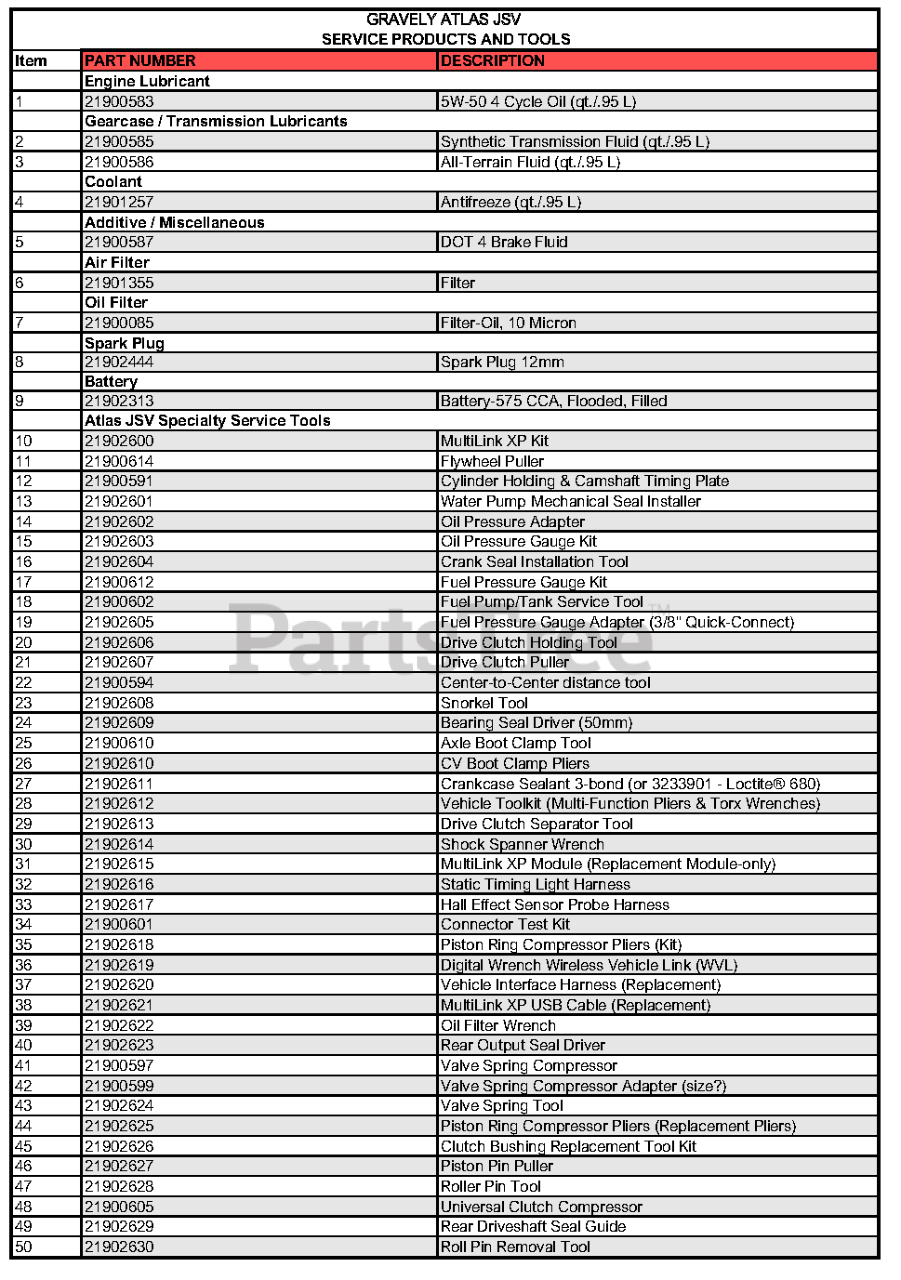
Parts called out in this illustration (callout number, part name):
1	5W-50 SYNTHETIC, 1 QT
2	TRANSMISSION FLUID-SYN, 1 QT
3	ALL TERRAIN FLUID, 1 QT
4	ANTI-FREEZE, ARIENS, 1QT
5	BRAKE FLUID-DOT 4, 12 OZ
7	FILTER-OIL,10 MICRON,(12)
8	SPARKPLUG-12MM
9	BATTERY-575 CCA,FLOODED,FILLED
10	MultiLink XP Kit
11	FLYWHEEL PULLER
12	Cylinder Holding & Camshaft Timing Plate
13	Water Pump Mechanical Seal Installer
14	Oil Pressure Adapter
15	Oil Pressure Gauge Kit
16	Crank Seal Installation Tool
17	Fuel Pressure Gauge Kit
18	Fuel Pump/Tank Service Tool
19	Fuel Pressure Gauge Adapter (3/8" Quick-Connect)
20	Drive Clutch Holding Tool
21	Drive Clutch Puller
22	Center-to-Center distance tool
23	Snorkel Tool
24	Bearing Seal Driver (50mm)
25	Axle Boot Clamp Tool
26	CV Boot Clamp Pliers
27	Crankcase Sealant 3-bond (or 3233901 - Loctite® 680)
28	Vehicle Toolkit (Multi-Function Pliers & Torx Wrenches)
29	Drive Clutch Separator Tool
30	Shock Spanner Wrench
31	MultiLink XP Module (Replacement Module-only)
32	Static Timing Light Harness
33	Hall Effect Sensor Probe Harness
34	Connector Test Kit
35	Piston Ring Compressor Pliers (Kit)
36	Digital Wrench Wireless Vehicle Link (WVL)
37	Vehicle Interface Harness (Replacement)
38	MultiLink XP USB Cable (Replacement)
39	Oil Filter Wrench
40	Rear Output Seal Driver
41	Valve Spring Compressor
42	Valve Spring Compressor Adapter (size?)
43	Valve Spring Tool
44	Piston Ring Compressor Pliers (Replacement Pliers)
45	Clutch Bushing Replacement Tool Kit
46	Piston Pin Puller
47	Roller Pin Tool
48	Universal Clutch Compressor
49	Rear Driveshaft Seal Guide
50	Roll Pin Removal Tool
